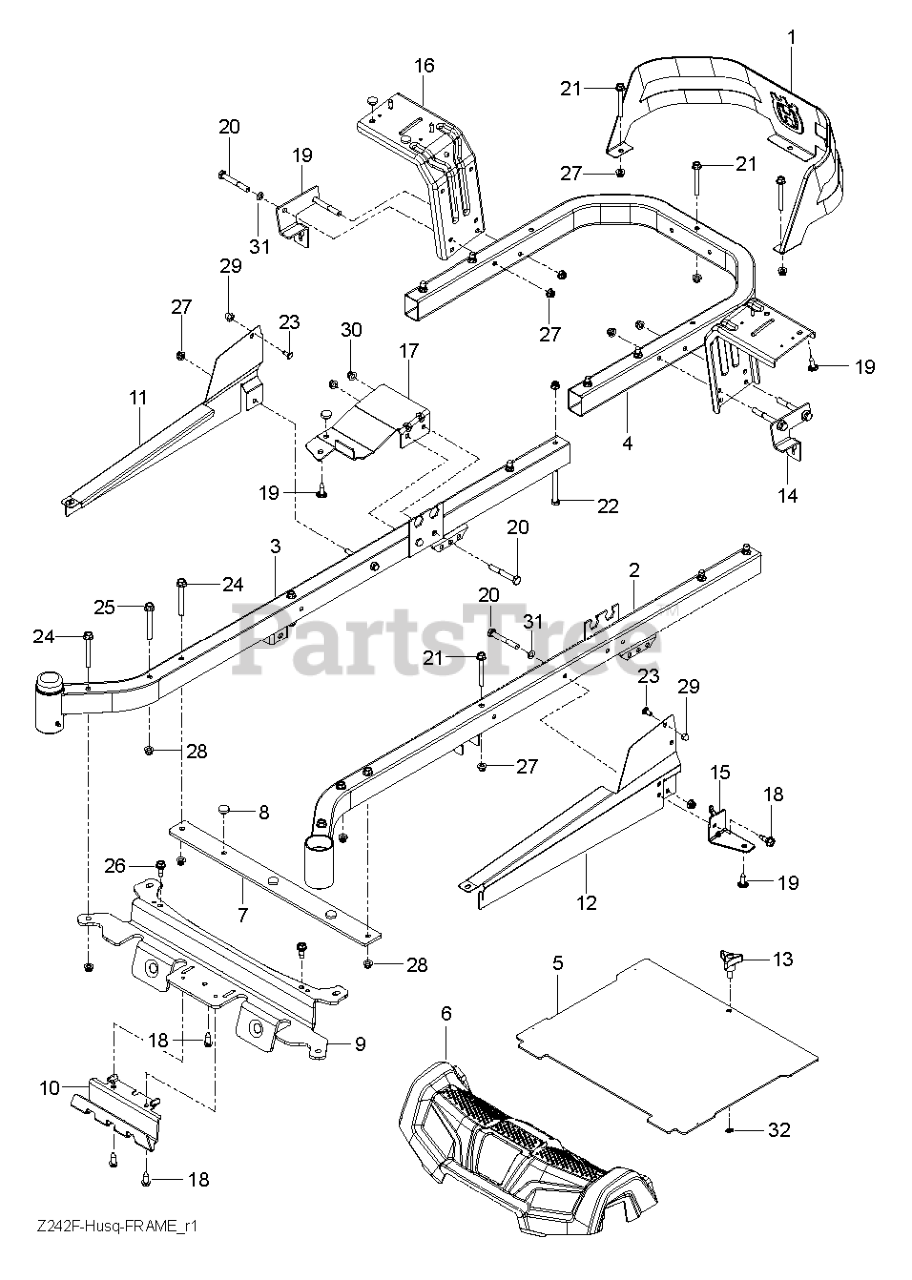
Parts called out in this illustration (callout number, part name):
1	GUARD.ENGINE.HUSQ.RZ.X498
2	FRAME.TUBE.RZ.MAIN.WELD.LH.ORG
3	FRAME.TUBE.RZ.MAIN.WELD.RH.ORG
4	TUBE.PNT.FRAME.RER.HUSQ.23".RZ
5	PLATE, FOOT W/DECALS RZ
6	COVER.FOOTREST.REFRESH.ASM
7	FOOTREST.PLATE.SUPPORT.X431
8	GROMMET.BUMPER
9	CROSS.PNT.MEMBER.BLK
10	SKID.PLATE.PNT.RZ.REF.SIVER
11	COVER.RAIL.RH.RZ.X668
12	COVER.RAIL.LH.RZ.X668
13	KNOB W/STUD
14	BRKT ROD.BYPASS.EZT.X431
15	SUPPORT.PNT.LH.CONSOLE.FRONT
16	FENDER.SUPPORT.PNT.X431
17	SUPPORT.PNT.RH.CONSOLE.FRONT
18	BOLT.5/16HEX.WHS.HD
19	SCREW.#10 X 0.750.BOS
20	BOLT.FIN HEX 5/16-18UNC X2 1/4
22	BOLT.HEX.FIN.3/8-16 X 3.GR5
23	BOLT.CARRIAGE.5/16-18.7/16
24	HHFS 3/8-16 X 3 GRD 5 ZD
25	BOLT SHOULDER,FLANGED,3/8-16X3
26	BOLT.5/16-18.THRD.ROLL.SHOULDR
27	5/16-18 NYLOC FLANGE NUT
28	NUT 3/8-16 HEX FLG NYLOC ZD
29	NUT ACORN,FLANGED,5/16-18
30	NUT LOCK HEX FLANGE 5/16-18
31	WASHER
32	WASHER 5/16"
